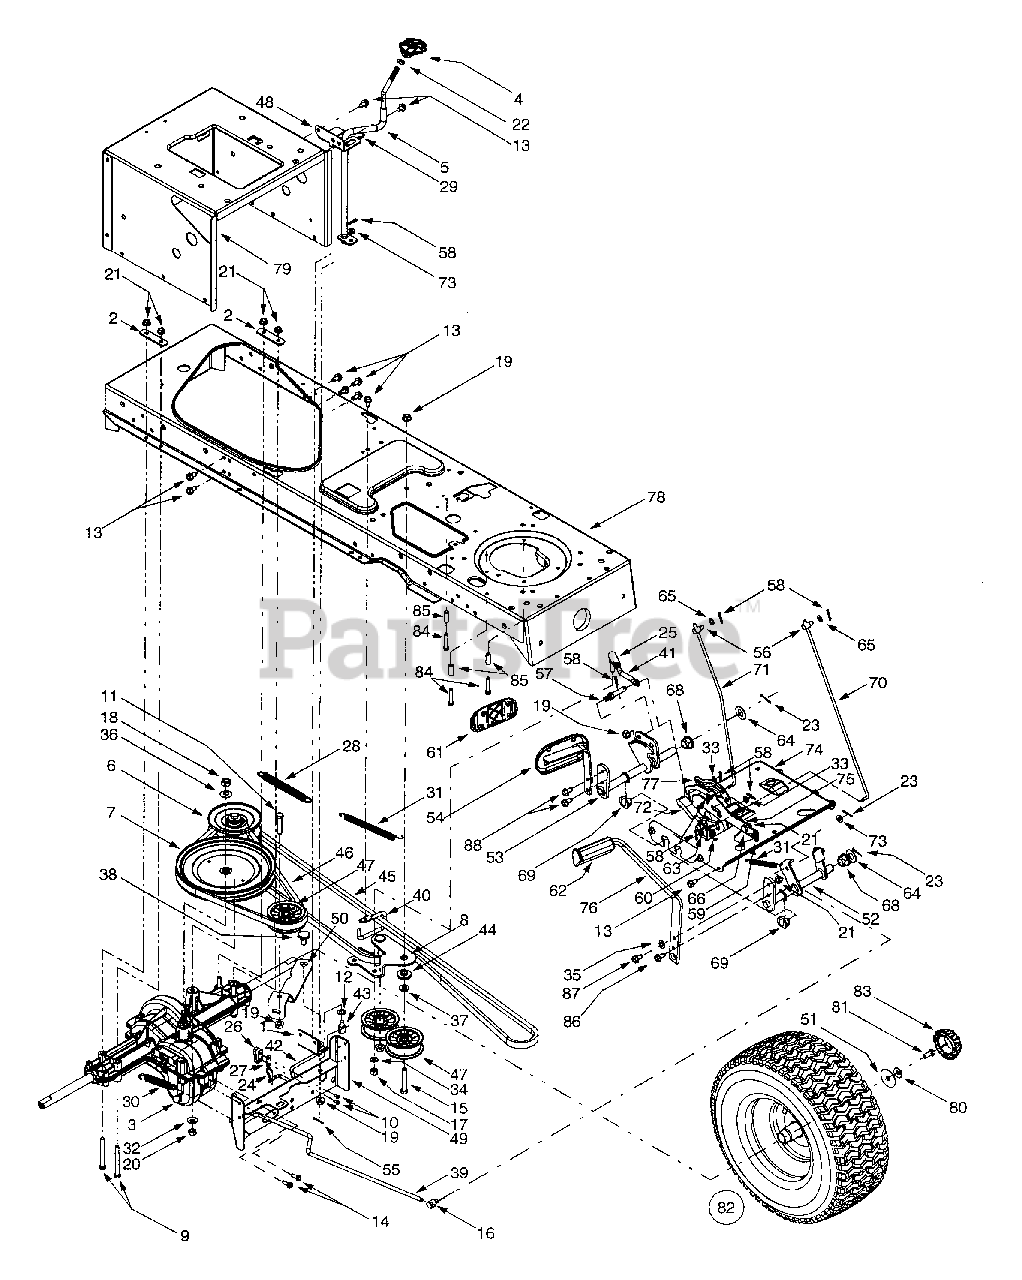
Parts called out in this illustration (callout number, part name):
1	Shift Lever Support
2	Transaxle Mounting Bracket
3	Single-speed Transmission Assembly
4	Shifter Knob
5	Shift Lever
6	Variable-speed Pulley Assembly
7	Transmission Pulley, 8.5 x .5-36
8	Double-idler Bracket
9	Hex Cap Screw, 5/16-18 x 2.75
10	Self-tapping Screw, #8-18 x .5
11	Hex Cap Screw, 3/8-16 x 1.75
12	Flat Washer, .51 x 1.0 x .060
13	Self-tapping Screw, 5/16-18 x .625
14	Self-tapping Screw, 1/4-20 x .75
15	Hex Cap Screw, 3/8-16 x 2.25
16	Ferrule, 5/16-18
17	Hex Nut, 3/8-24
18	Hex Nut, 7/16-20
19	Flange Lock Nut, 3/8-16
20	Hex Nut, 3/8-16
21	Flange Lock Nut, 5/16-18
22	Jam Nut, 3/8-16
23	Cotter Pin
24	Internal Cotter Pin
25	Ball Joint
26	Short Spring Switch
27	Insulator Nut Plate
28	Extension Spring, .62 Dia. x 6.12
29	Compression Spring Clip
30	Extension Spring, .59 OD x 4
31	Extension Spring, .50 Dia. x 6.37
32	Bell Washer, .401 x .87 x .063
33	Flat Washer, .385 x .62 x .063
34	Lock Washer, 3/8
35	Flat Washer, .344 x .750 x .120
36	Bell Washer, .45 x 1.0 x .602
37	Flat Washer, .407 x .812 x .135
38	Shoulder Screw, .625 x .217
39	Brake Rod
40	Belt Guard
41	Idler Adjustment Rod, 3/8
42	Shift Rod
43	Adjustment Ferrule, 1/4-20 x 1.0
44	Shoulder Spacer, .38 ID
45	Lower Drive Belt
46	Upper Drive Belt
47	Flat Idler, 2.75 OD
48	Speed Control Rod Bracket
49	Transmission Torque Bracket
50	Idler Bracket
51	Flat Washer, .350 x 1.59 x .062
52	Brake Control Assembly
53	Speed Control Assembly
54	Drive Pedal Assembly
55	Cotter Pin, 1/8 x 1.25
56	Ferrule, 1/4-20
57	Pin, 3/8-16 x 2.43
58	Cotter Pin
59	Compression Spring, .34 OD x 1.0
60	Extension Spring, .50 OD x 1.41
61	Drive Pedal Pad
62	Brake Pedal Pad
63	Flat Washer, .281 x .5 x .063
64	Flat Washer, .64 x 1.24 x .06
65	Flat Washer, .344 x .062 x .03
66	Shoulder Screw, .437 x 1.62
67	Shoulder Screw, .5 x .434
68	Hex Flange Bearing
69	Split Hex Flange Bearing
70	Cruise Control Rod
71	Brake Lock Control Rod
72	Cruise Latch
73	Flat Washer, .344 x .688 x .065
74	Stearing Support Bracket
75	Drive Lockout Bracket
76	Brake Pedal
77	Neutral Return Bracket
78	Lower Frame Assembly
79	Hitch Plate
80	Bell Washer, .34 x .872
81	Hex Cap Screw, 5/16-24 x .75
82	Wheel Assembly Complete, 20 x 8 x 8
83	Hub Cap
84	Self-tapping Screw, 1/4-20 x 1.25
85	Spacer
86	Self-tapping Screw, 5/16-18 x .875
87	Self-tapping Screw, 5/16-18 x .75
88	Self-tapping Screw, 5/16-18 x .75
